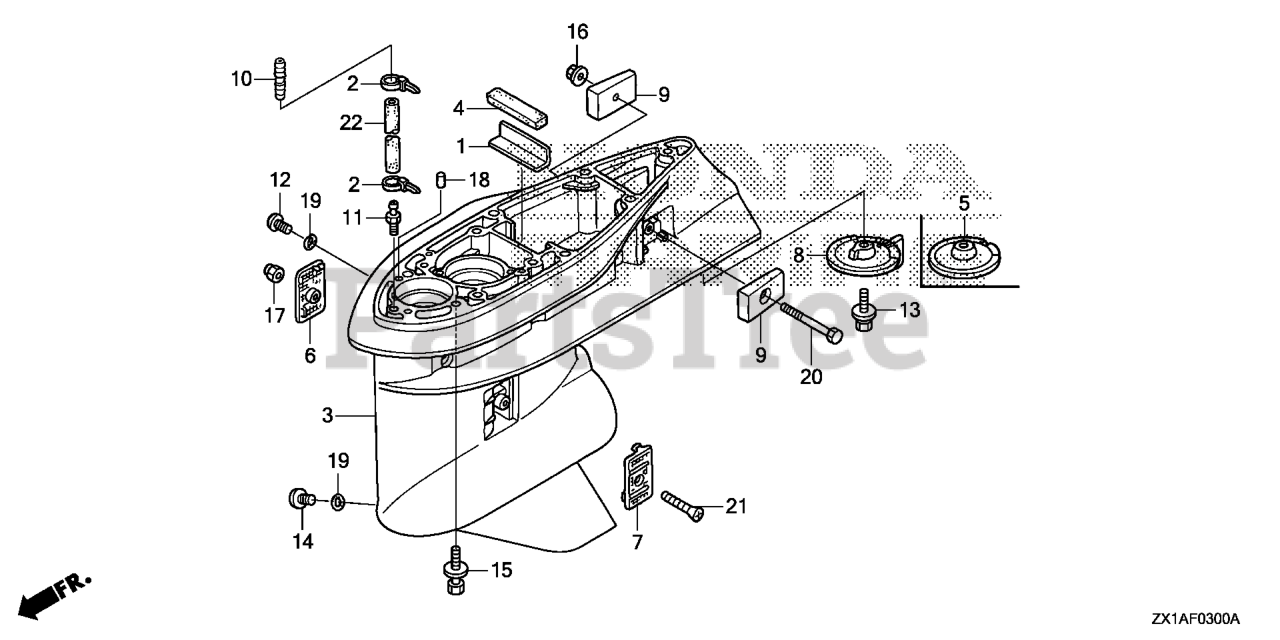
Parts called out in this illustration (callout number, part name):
1	PLATE, RUBBER SETTING
2	BAND, WIRE
3	CASE, GEAR *NHB14M* (AQUA MARINE SILVER METALLIC)
3	CASE,GEAR*NH565*
4	GROMMET, GEAR CASE
6	SCREEN, R. WATER
7	SCREEN, L. WATER
8	TAB, TRIM *NHB14M* (AQUA MARINE SILVER METALLIC)
8	TAB, TRIM *NH565* (GRAND PRIX WHITE)
9	METAL, ANODE
10	END, NIPPLE
11	NIPPLE, SENSOR
12	BOLT, OIL CHECK
13	BOLT-WASHER (10X32)
14	BOLT, DRAIN PLUG
15	BOLT-WASHER (10X40)
16	NUT, SELF-LOCK (6MM)
17	NUT, SELF-LOCK (5MM)
18	PIN, DOWEL (6X10)
19	O-RING (6.9X1.45)
20	BOLT, HEX. (6X50)
21	SCREW, OVAL (5X50)
22	BULK HOSE, VACUUM (5X3000) (5X250)
